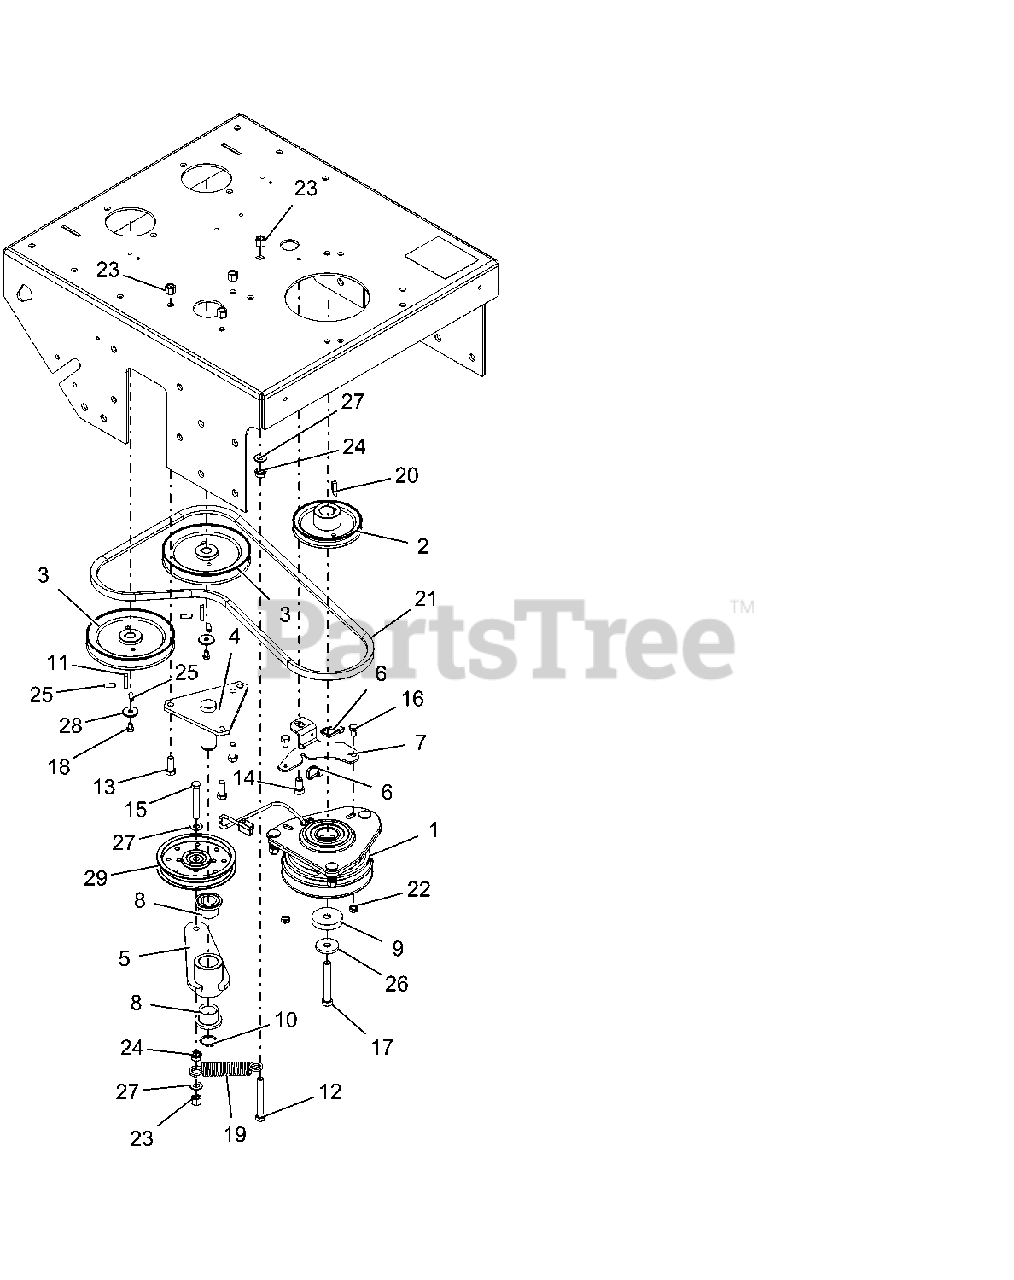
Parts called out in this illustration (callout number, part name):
1	CLUTCH ASSY, OGURA
2	PULLEY, V-BELT WLK TRANS DRIVE
3	PULLEY, V-BELT PUMP HYD WLK
4	WLDMT, IDLER PIVOT MOUNT
5	WLDMT, IDLER ARM
6	CABLE TIE, .15 X 8.50
7	PLATE, CLUTCH DOG
8	BRG, FLANGE 1.00 X 1.25 X 1.00
9	SPCR, .450 X 2.00 X .396
10	SNAP, RING, 1.00 X .042 EXT
11	KEY, RND - M5XM5XM30
12	BLT-HEX .38-16X3.00 GR8 YWZC
13	BLT-HEX .38-16X1.00 GR5 YWZC
14	BLT-HEX .44-14X.75 GR5 YWZC
15	BLT-HEX .38-16X2.50 GR5 YWZC
16	BLT-HEX .31-18X.50 GR5 YWZC
17	BLT-HEX .44-20X3.00 GR8 YWZC NYTORQ
18	BLT-HEX M6 X 1.0X10 YWZC
19	SPRG, EXTENSION
20	KEY, .250 X .250 X .995 TPR
21	BELT, HA 55.1 EL AMD OHR
22	NUT-LK-CTR-JAM .31-18 YWZC
23	NUT-LK-NYL .38-16 YWZC
24	@NUT-SPNLK-FLG .375-16 YWZC
25	SCR-SET, 25-20X.75 SKHCUPDL REV
26	WSHR, 7/16" SPRING DISC
27	WSHR-FL-STL.406X.812X.065 YWZ
28	WASHER, .250 WIDE HEAVY FLAT Y
29	PULLEY, FLAT 4.50 X .375 W/BRG
